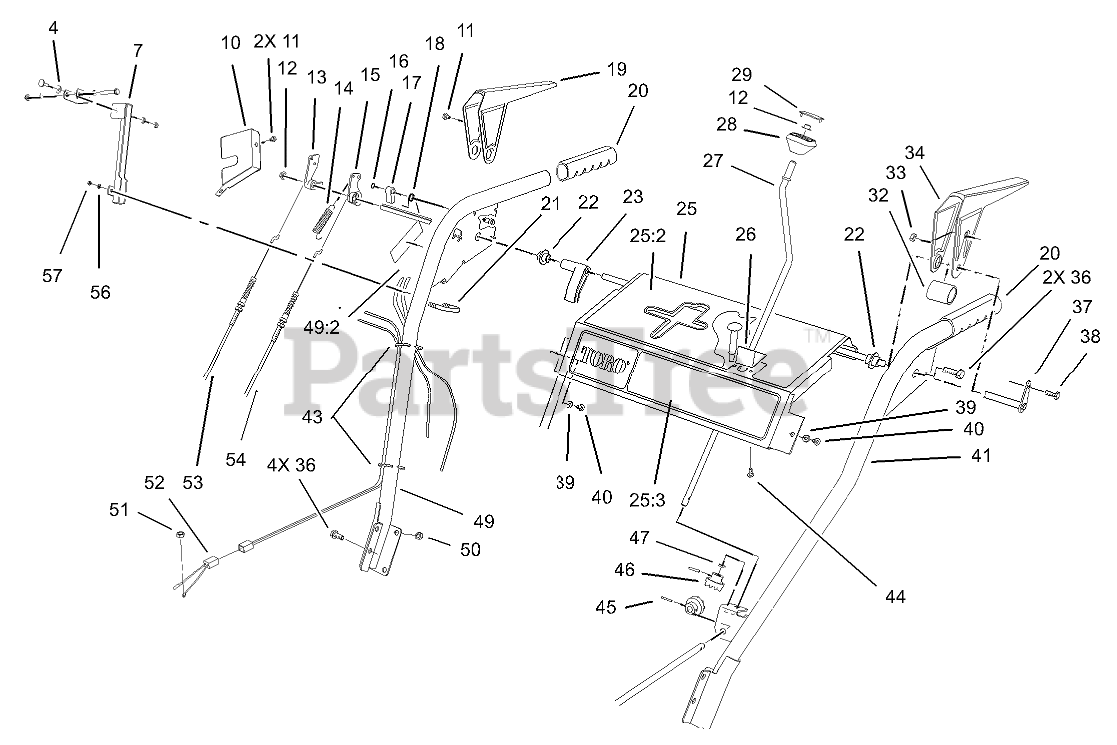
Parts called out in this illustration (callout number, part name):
4	WASHER-FLAT
7	LIGHT MOUNT ASM
10	COVER-LOCK, LEVER
11	SCREW-HH
12	RETAINER-PUSH ON
13	TANG-LOCKING
14	SPRING-EXTENSION
15	CAM-RELEASE
16	E-RING-RETAINER
17	LATCH-LOCKING
18	SPRING-TORSION
19	LEVER-TRACTION, RH
20	GRIP-HANDLE
21	U-BOLT
22	BUSHING-LEVER
23	LEVER-TRIP
25	CONTROL PANEL ASM
25:2	DECAL-CONTROL
25:3	DECAL - FRONT PANEL
26	PLATE-GUIDE
27	CRANK-ROD, CHUTE
28	KNOB-CONTROL, CHUTE
29	COVER-KNOB
32	SPACER-LEVER, TRACTION
33	NUT-LOCK, NI
34	LEVER-TRACTION, LH
36	SCREW-HWHTF
37	CROSS ROD ASM
38	SCREW-HWH
39	WASHER-FLAT
40	SCREW-HWHTF
41	LH HANDLE ASM
43	TIE-CABLE
44	SCREW
45	PIN-SPRING
46	GEAR-UNIVERSAL
47	WASHER-RUBBER
49	HANDLE ASM
49:2	DECAL-ADJUSTMENT
50	NUT-LOCK, NI
51	NUT-HEX
52	WIRE ASM
53	CABLE-IMPELLER
54	CABLE-TRACTION
56	WASHER-PLAIN
57	NUT-LOCK, NI
